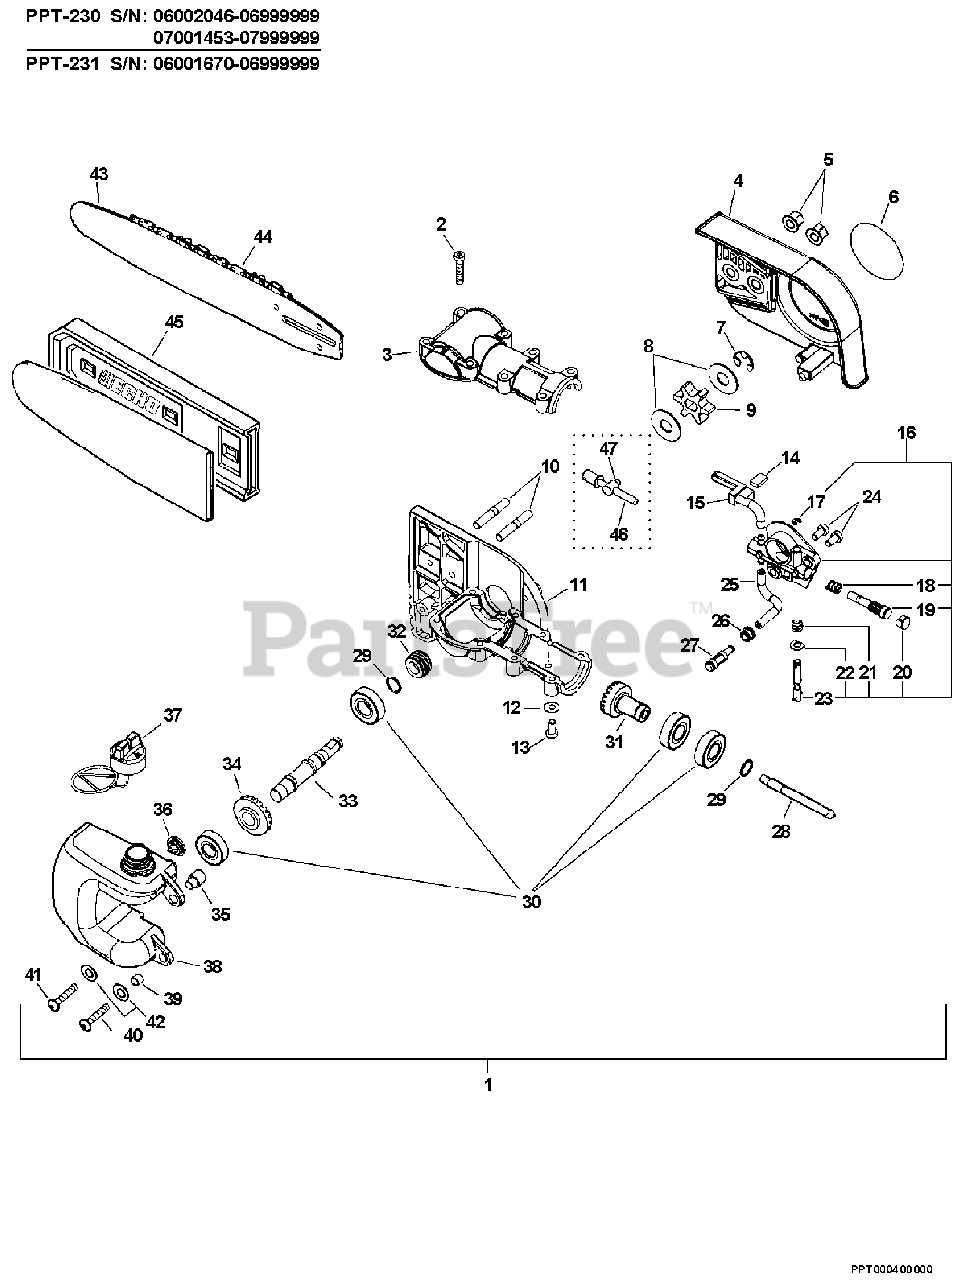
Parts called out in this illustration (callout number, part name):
1	CASE ASSY, OILER/GEAR
2	BOLT 5×0.8×25
3	CASE, GEAR - UPPER Ø35
4	GUARD, SPROCKET
5	NUT, FLANGE M6
6	LABEL, ECHO
7	RING, RETAINING Ø0.300
8	WASHER 10.2×24.5×1.2
9	SPROCKET, DRIVE
10	BOLT, STUD 6
11	CASE ASSY, LOWER GEAR
12	WASHER, FLAT 5.5×10×0.8
13	BOLT 5×10
14	PAD, FOAM
15	PIPE, OIL OUTLET
16	AUTO-OILER ASSY
19	PLUNGER ASSY
20	CAP, OIL PUMP
23	ADJUSTER, OILER
24	BOLT 5×10
25	PIPE, IMPULSE 3×6×75
26	GROMMET
27	FILTER, OIL
28	CONNECTOR, DRIVE SHAFT
29	RING, SNAP Ø12
30	BEARING, BALL
31	GEAR, BEVEL - 15 TOOTH
32	GEAR, WORM
33	SHAFT, GEAR
34	GEAR, BEVEL
35	COLLAR 6
36	VENT ASSY
37	CAP ASSY, OIL
38	TANK, OIL
39	SPACER 6.2×7.8×6
40	BOLT 5×16
41	BOLT 5×0.8×25
42	WASHER 5.5×12×0.8
43	GUIDE BAR - 10" -- INTENZ
44	SAWING CHAIN - 91VS - 10" -- LOW PROFILE
45	SCABBARD 10"
46	BOLT 5
47	TENSIONER, CHAIN
